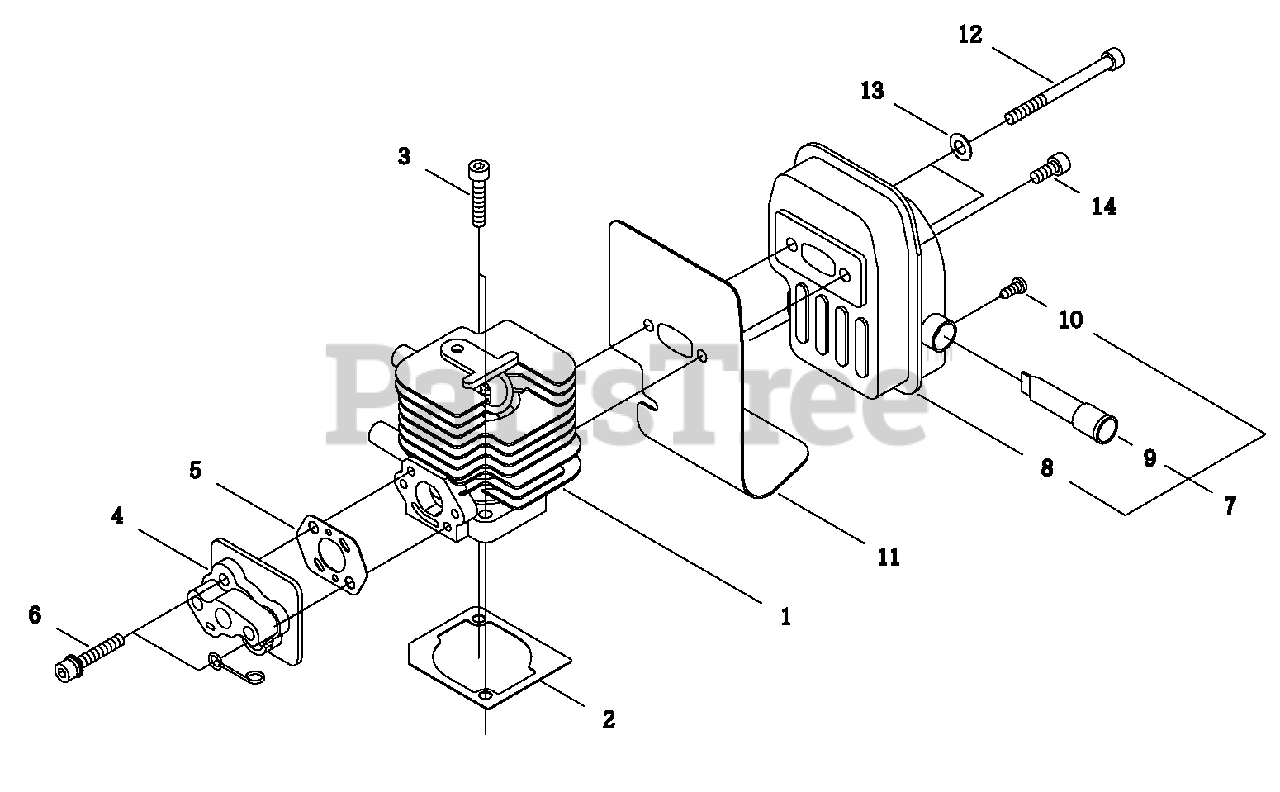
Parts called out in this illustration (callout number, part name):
1	CYLINDER
2	GASKET, CYLINDER
3	SCREW - 5X25
4	INSULATOR, INTAKE
5	GASKET, INTAKE
6	SCREW - 5X30
7	MUFFLER ASSY
8	MUFFLER
9	SCREEN, SPARK ARRESTOR
10	SCREW - 3X6
11	SHIELD, EXHAUST
12	SCREW - 5X50
13	WASHER - 5
14	SCREW - 5X12
